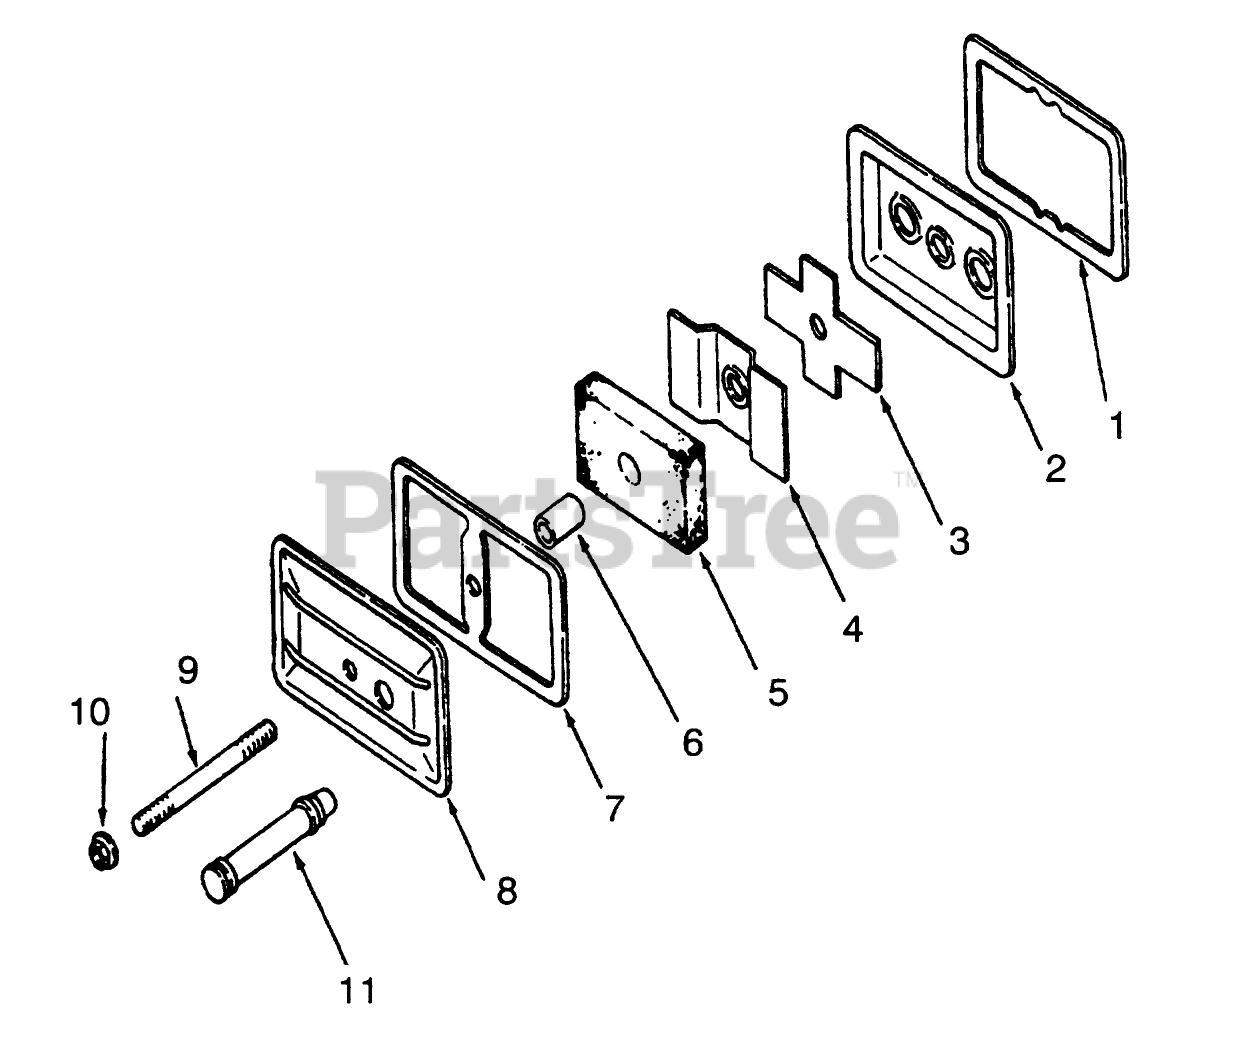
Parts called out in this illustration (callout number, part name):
1	KOHLER 235048
2	KOHLER 235631
3	KOHLER 235047
4	KOHLER 270146
5	KOHLER 47-050-01
6	KOHLER 231032
7	KOHLER 275144
8	KOHLER 47-096-01
9	KOHLER 275220
10	KOHLER X-799-1
11	KOHLER 47-326-03
